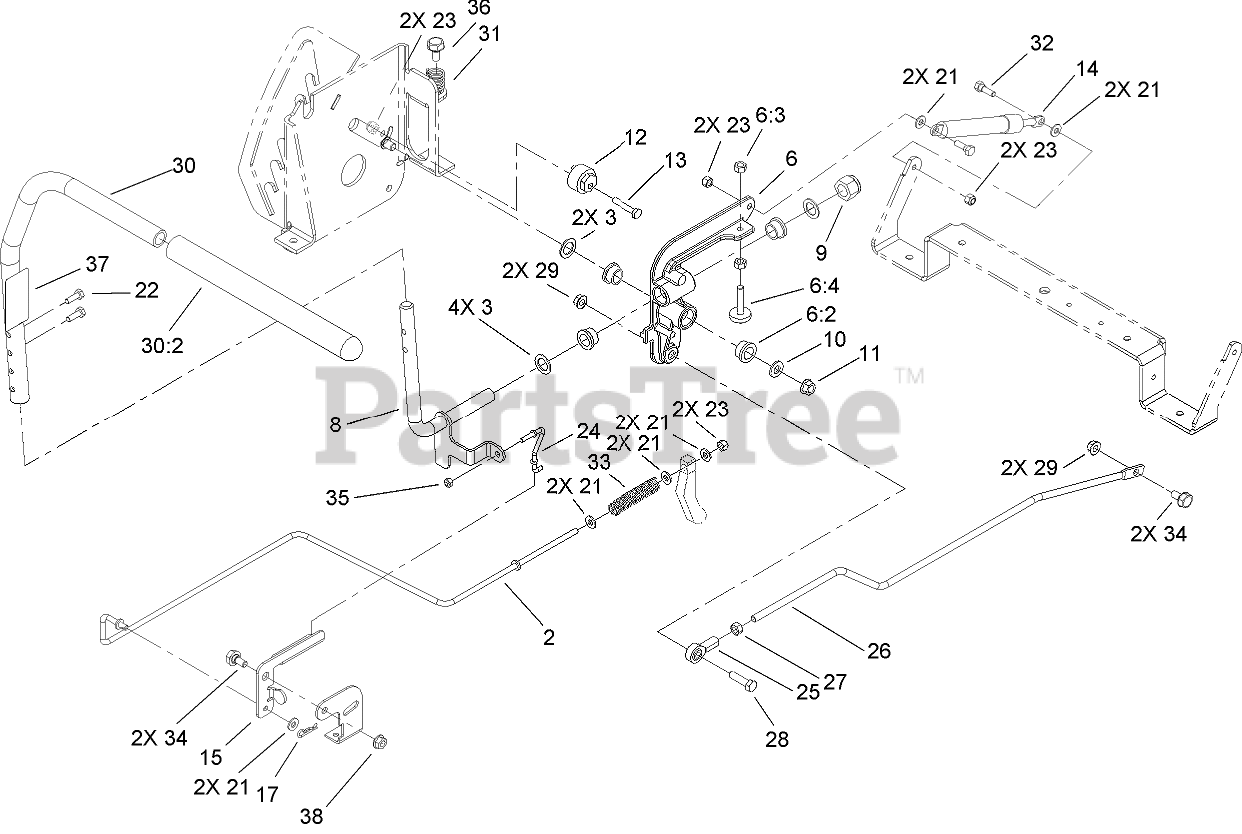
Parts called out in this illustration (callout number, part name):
2	ROD-BRAKE, RH
3	WASHER-THRUST
6	RH ACTIVATOR ARM ASM
6:2	BUSHING
6:3	NUT-HEX
6:4	STOP-ADJUSTMENT
8	RH PIVOT SHAFT ASM
9	NUT-LOCK, NI
10	WASHER-FLAT
11	NUT-LOCK, NI
12	ECCENTRIC
13	SCREW-HH
14	Damper-Control, Motion
15	BELLCRANK
17	PIN-COTTER
21	WASHER-FLAT
22	SCREW-HH
23	NUT-LOCK, NI
24	LINK-BRAKE
25	BALLJOINT-RH
26	ROD-HYDRO
27	NUT-HEX
28	SCREW-HH
29	NUT-HF
30	HANDLE ASM
30:2	GRIP-CONTROL, MOTION
31	SPRING-COMPRESSION
32	BOLT-SHOULDER
33	SPRING-COMPRESSION
34	BOLT-SHOULDER
35	NUT-LOCK, NI
36	SCREW-HSH
38	NUT-HF
